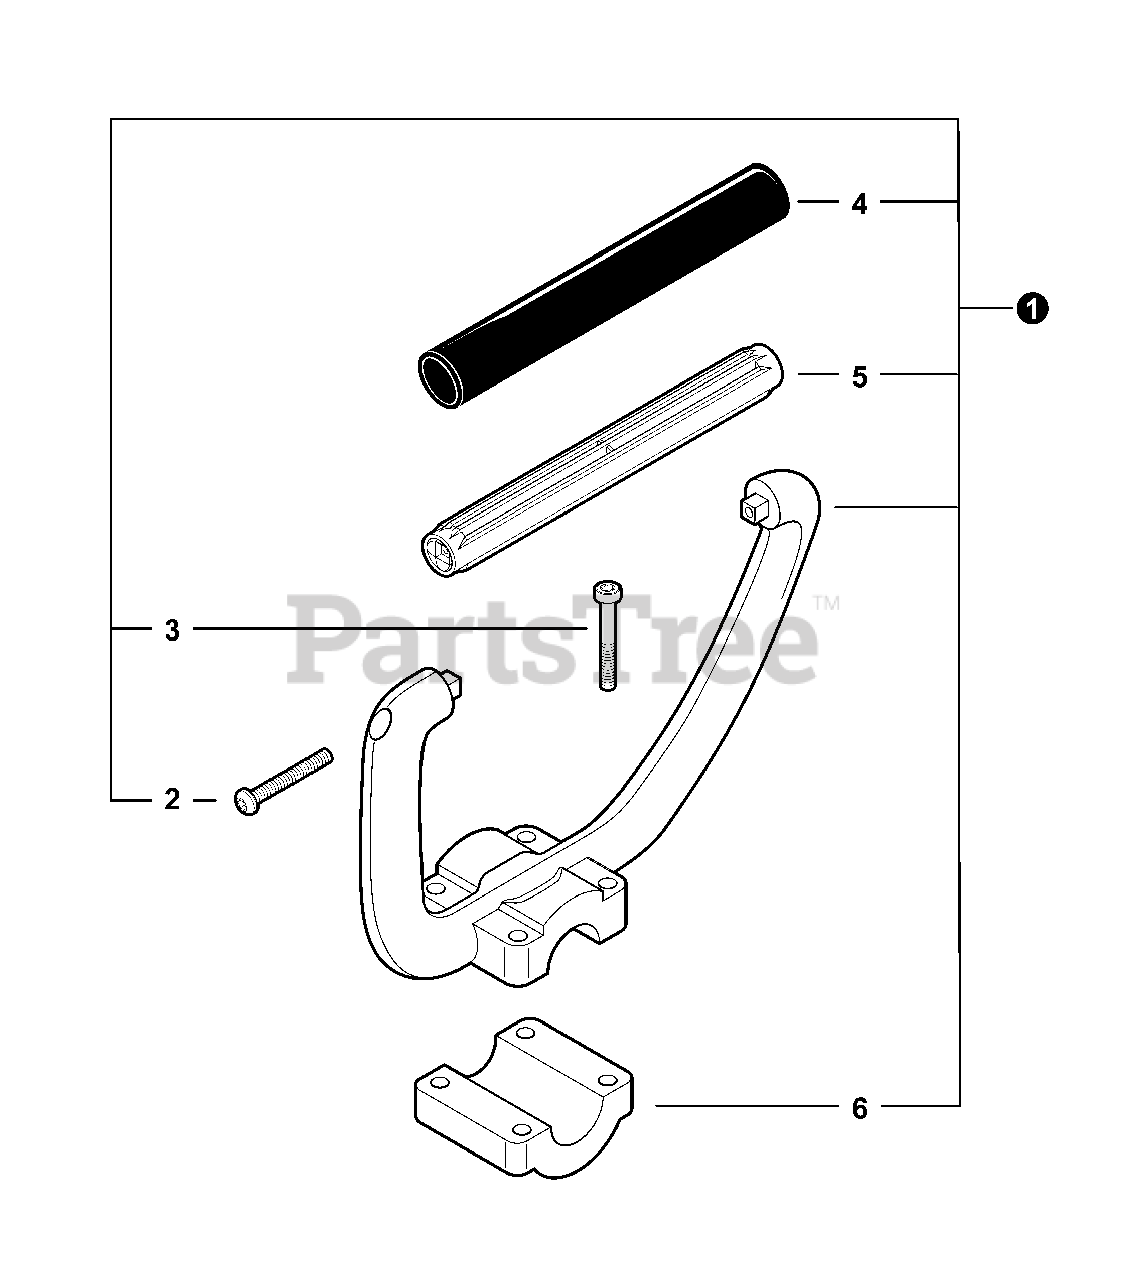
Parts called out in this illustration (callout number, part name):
1	HANDLE ASSY - SUPPORT
2	SCREW 5×30
3	SCREW 5×35
4	GRIP, HANDLE
6	BRACKET, HANDLE
